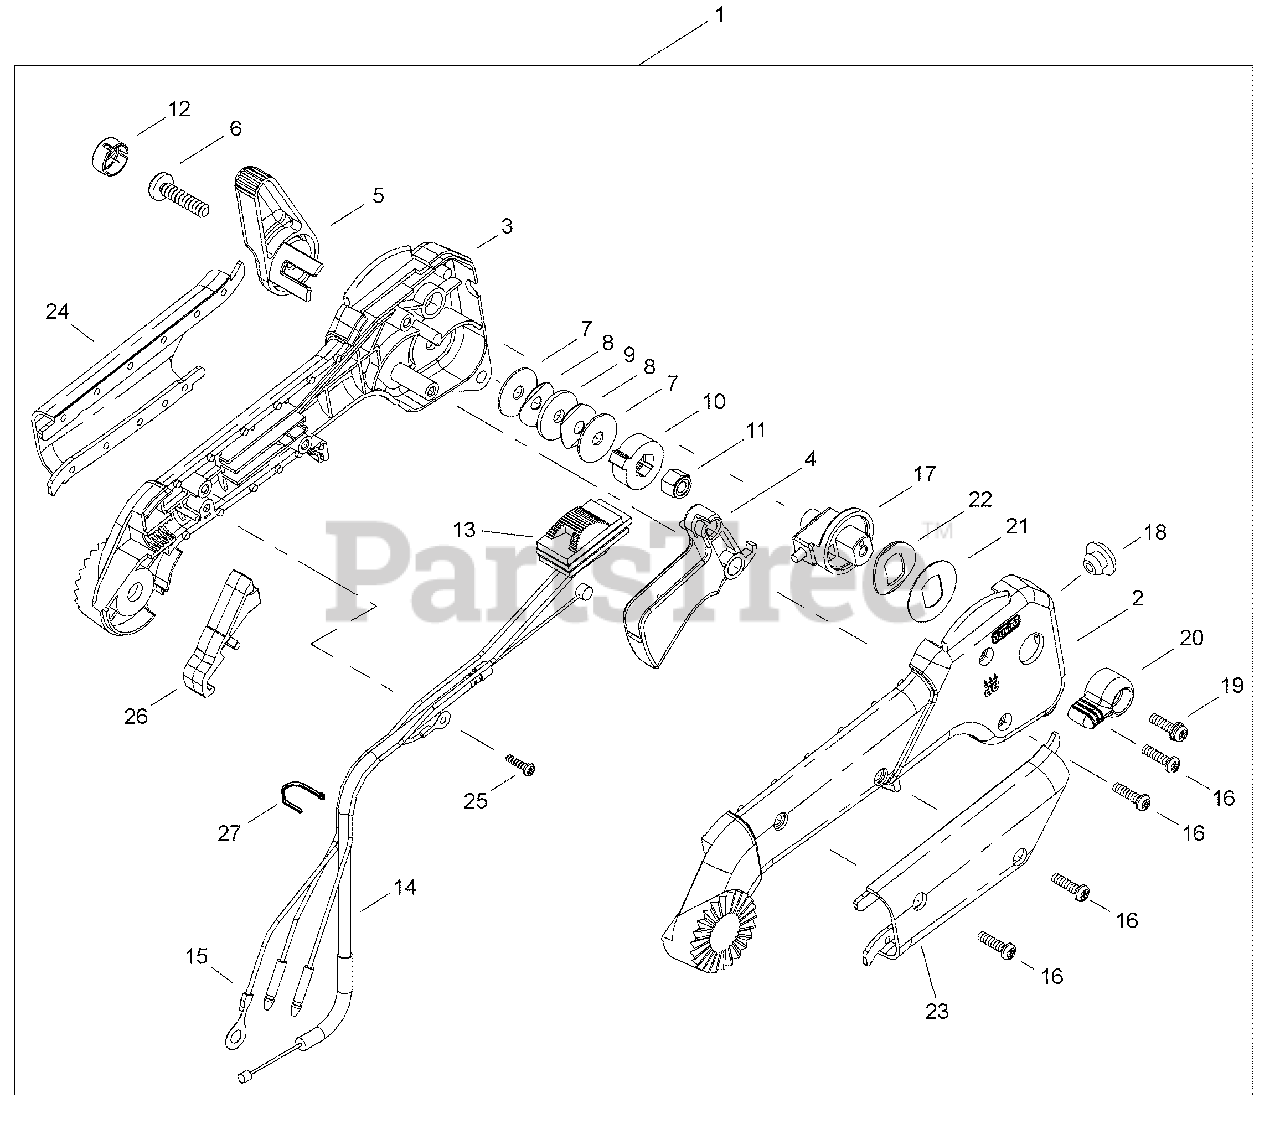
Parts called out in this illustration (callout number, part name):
1	THROTTLE CONTROL ASSY
2	CONTROL HANDLE - RIGHT
3	CONTROL HANDLE - LEFT
4	TRIGGER, THROTTLE
5	CONTROL, THROTTLE
6	BOLT M6×25
7	WASHER M6
8	WASHER, SPRING
9	WASHER M6
10	LEVER, THROTTLE
11	NUT, NYLON M6
12	CAP, BOLT
13	SWITCH, IGNITION
14	CABLE, THROTTLE
15	LEAD - GROUND
16	SCREW M4×16
17	LIMITER ASSY, THROTTLE
18	PLUG, THROTTLE LIMITER
19	SCREW M4×16
20	LEVER, THROTTLE LIMITER
21	WASHER
22	WASHER, WAVE
23	GRIP, RIGHT
24	GRIP, LEFT
25	SCREW M3×8
26	COVER, HANDLE REAR
27	BAND
